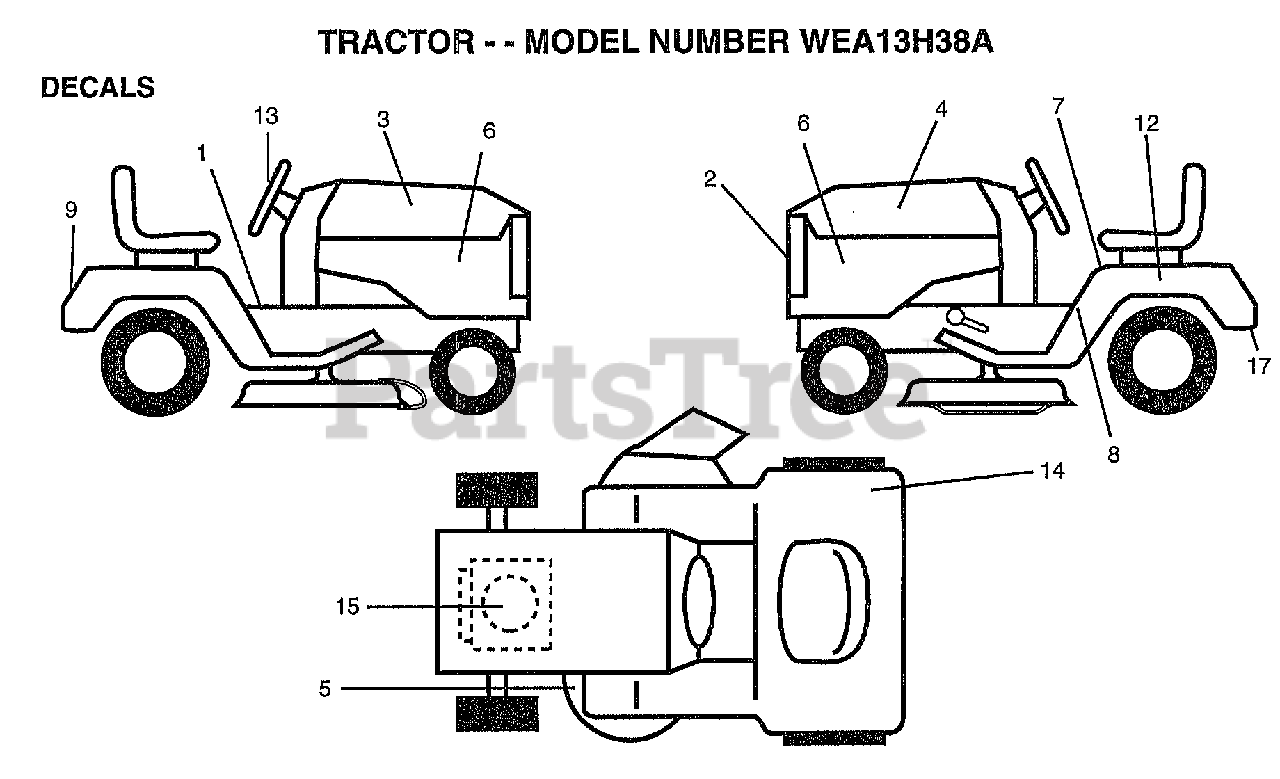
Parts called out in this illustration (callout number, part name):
1	DECAL.OPERATING
2	"DECAL,LIGHT BOX"
3	DECAL.HOOD.RH
4	DECAL.HOOD.LH
5	DECAL
6	DECAL.PANEL.SIDE
7	"DECAL DANGER,FEND"
8	DECAL
9	DECAL.FENDER.LOGO
12	DECAL.BATRY.3-3908
13	DECAL INSRT STEER
14	DECAL
15	DECAL.ENGINE
17	DECAL.DRAWBAR.CTL
